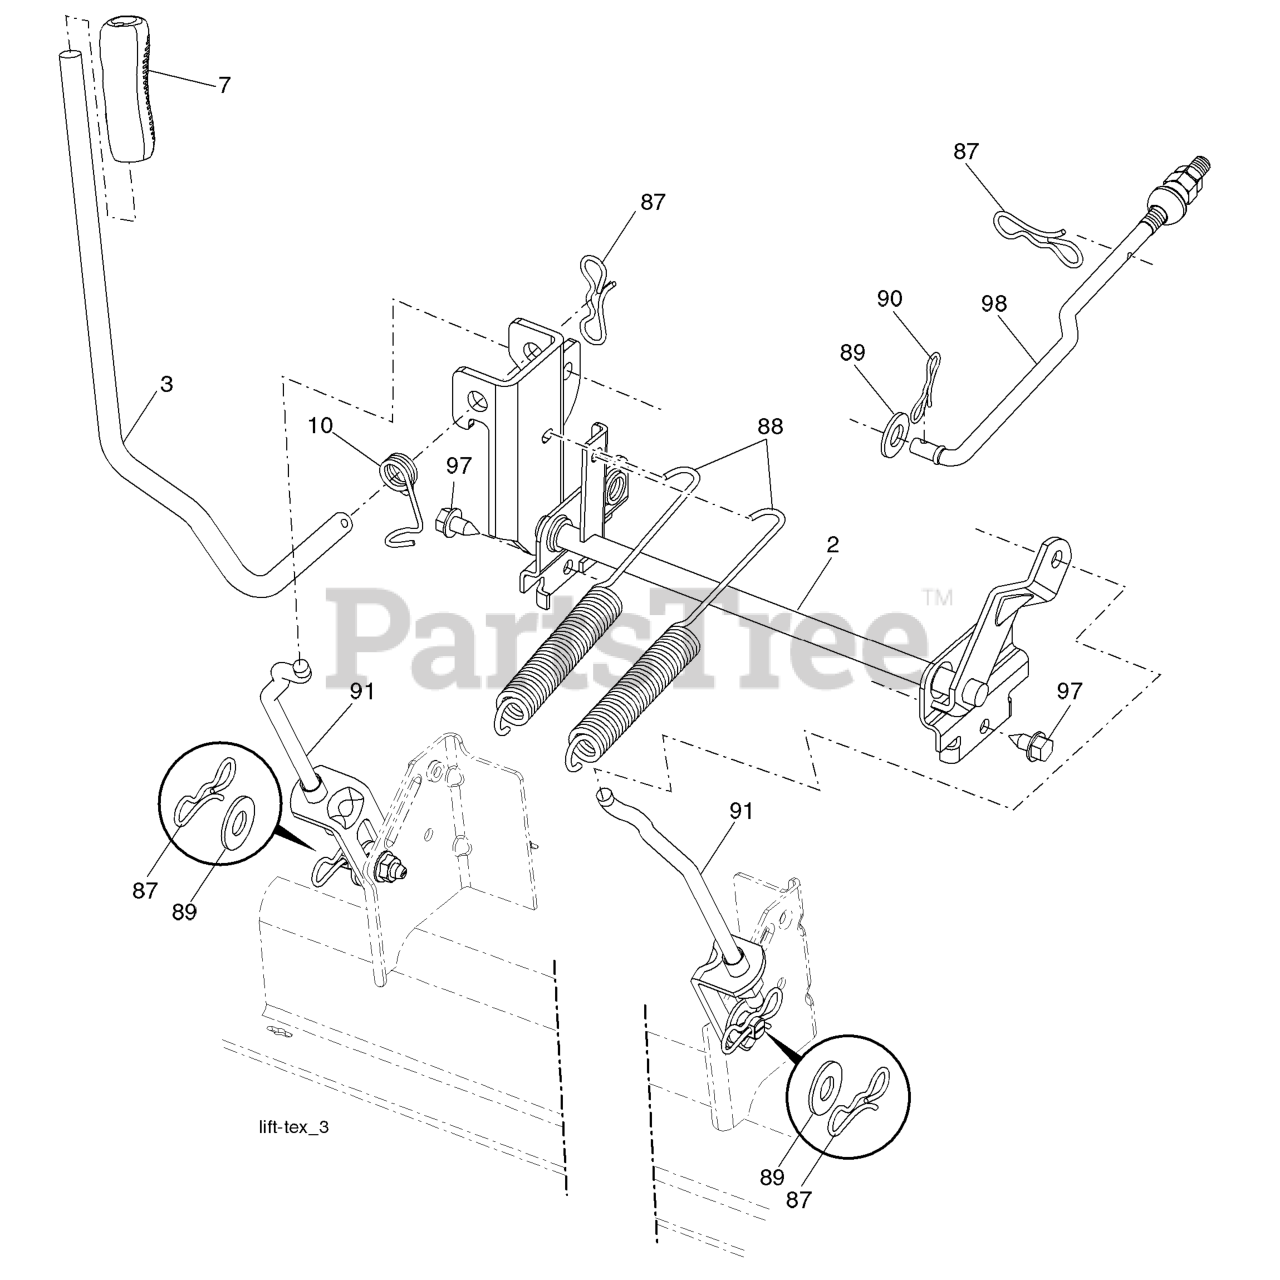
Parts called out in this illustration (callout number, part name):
2	SHAFT.ASM.LIFT.CROSS.H
3	LEVER.LIFT.HANDLE.GT
7	GRIP.HANDLE.LIFT.PVC.BLACK
10	SPRING.TORSION.LIFT.HANDLE
87	PIN.COTTER.7/16.BOW TI.
88	SPRING.LIFT.ASSIST.GT2
89	WASHER.CLEAR.ZINC
90	PIN.COTTER.5/16.BOW TI
91	LINK.LIFT.ASM.REAR.GT.
97	SCREW, 3/8-16X3/4
98	LINK.ASM.SUSP.FRONT.MWR.10.5
